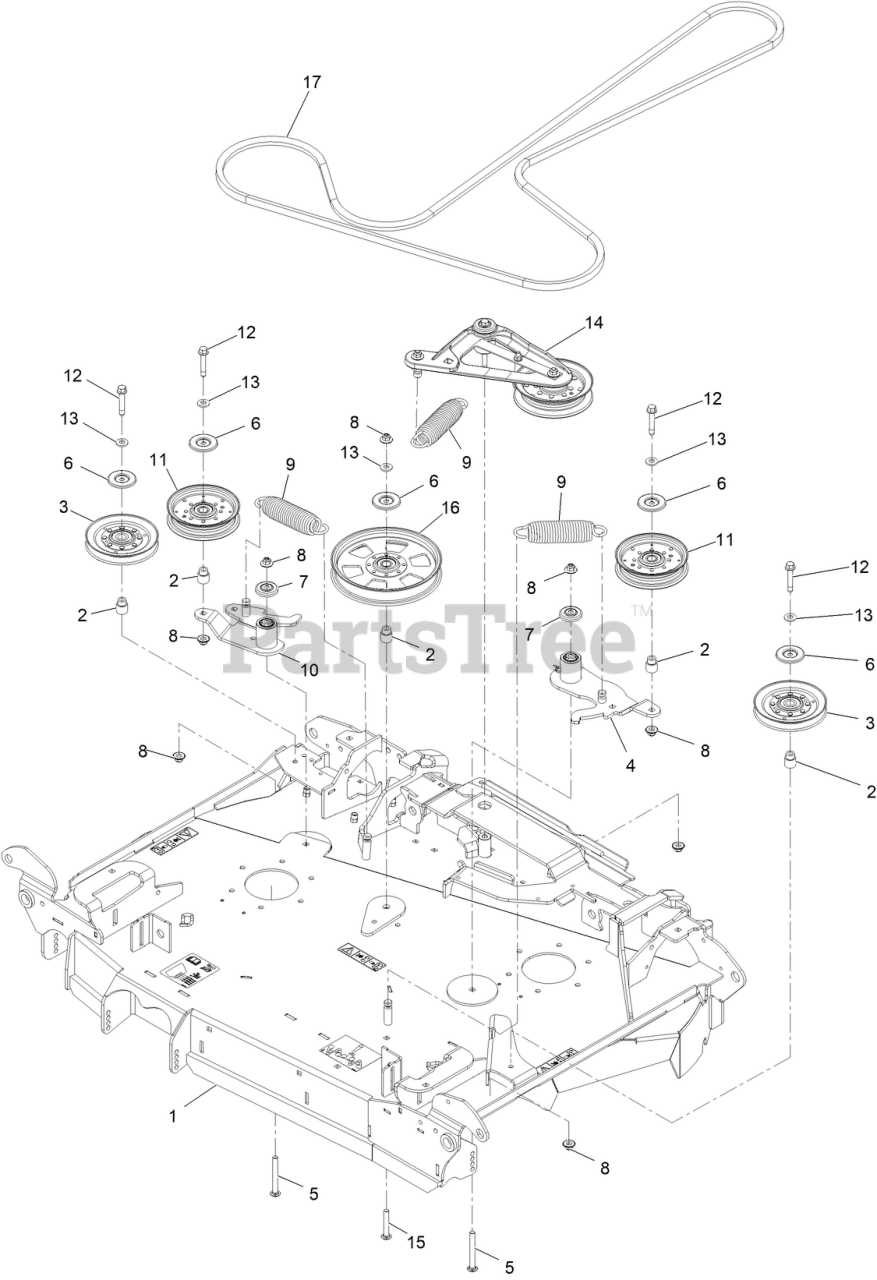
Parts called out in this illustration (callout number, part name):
1	ASM-Deck, Ctr 96G [exm]
2	BUSHING-IDLER
3	IDLER-V
4	IDLER ASM
5	BOLT-SHOULDER, CARRIAGE 3/8-16 X 3 1/2
6	SHIELD-DUST
7	GUARD-TOP
8	Nut-Nyloc 3/8-16 Flg
9	SPRING-EXTENSION
10	IDLER ASM
11	PULLEY-IDLER, FLAT
12	SCREW-HHF
13	WASHER-BELLEVILLE
14	DECK IDLER ASM
15	SCREW-CARR
16	PULLEY-IDLER, FLAT
